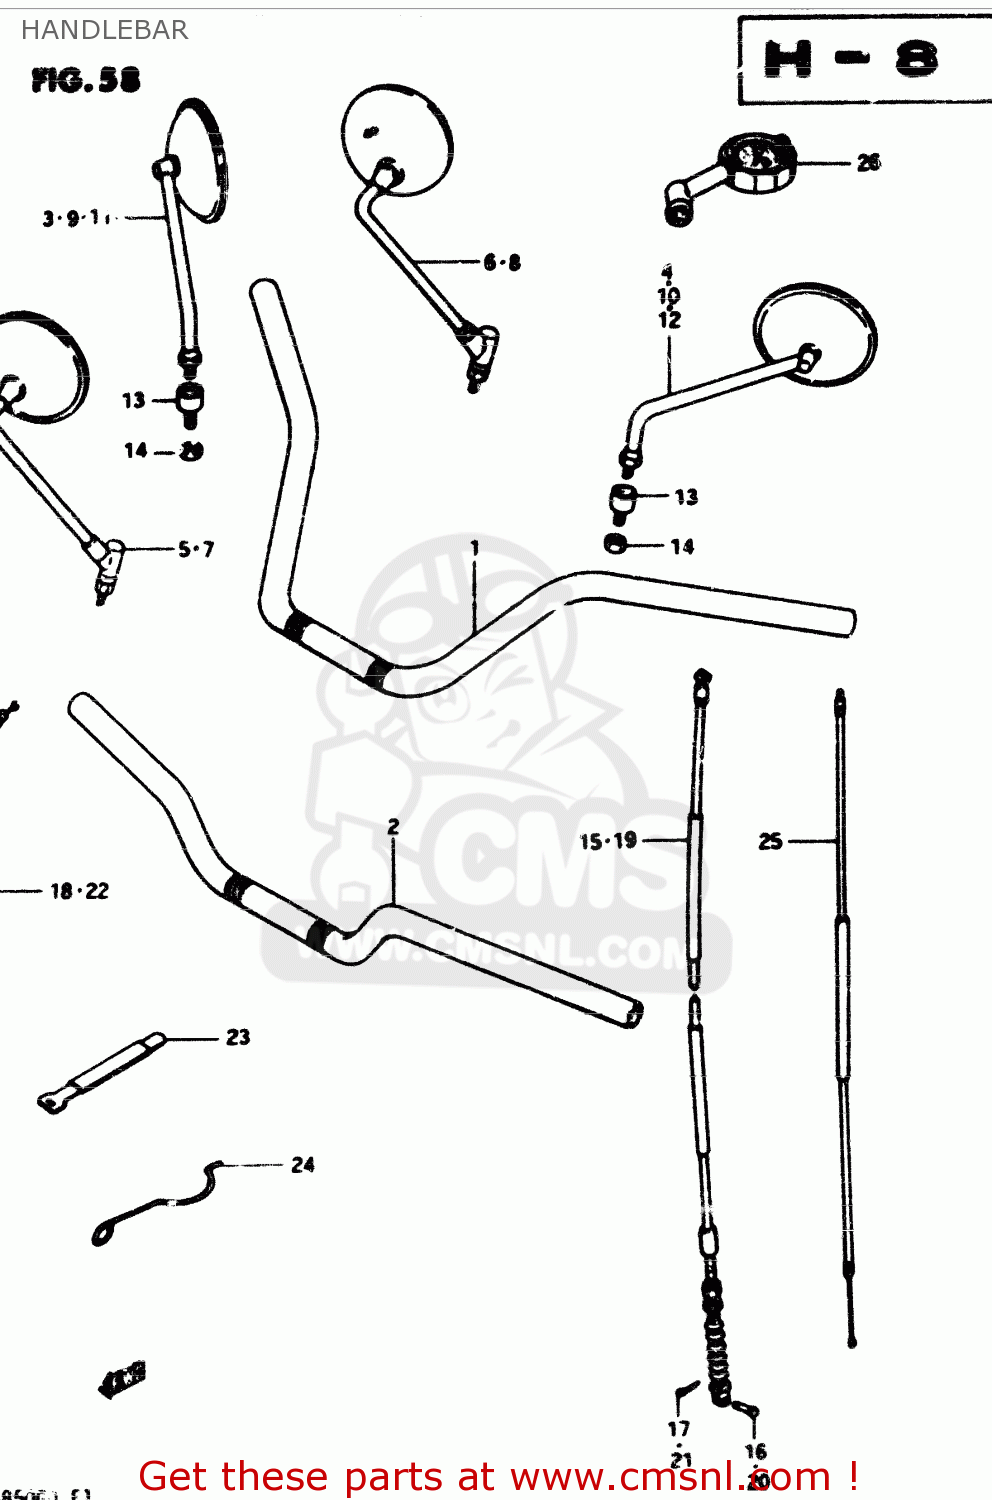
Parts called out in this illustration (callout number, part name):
1	HANDLEBAR
2	HANDLEBAR (FLAT)
3	MIRROR ASSEMBLY,RIGHT
4	MIRROR ASSEMBLY,LEFT
5	MIRROR ASSY,RH
6	MIRROR ASSY,RH
7	MIRROR ASSY,RH
8	MIRROR, REAR VIEW LH
9	MIRROR ASSY RH
10	MIRROR ASSY
11	MIRROR ASSY,RR VIEW,R
12	MIRROR, REAR VIEW LH
13	CUSHION,REAR VIEW MIRROR
14	NUT
15	CABLE ASSY,CLUTCH
16	PIN(L:15)
17	PIN
18	CABLE ASSEMBLY,THROTTLE
19	CABLE ASSY,CLUTCH
20	PIN(L:15)
21	PIN
22	CABLE ASSEMBLY,THROTTLE
23	CLAMP
24	GUIDE,CABLE
25	CABLE,STARTER
26	GAUGE ASSY,AIR PRESSURE
